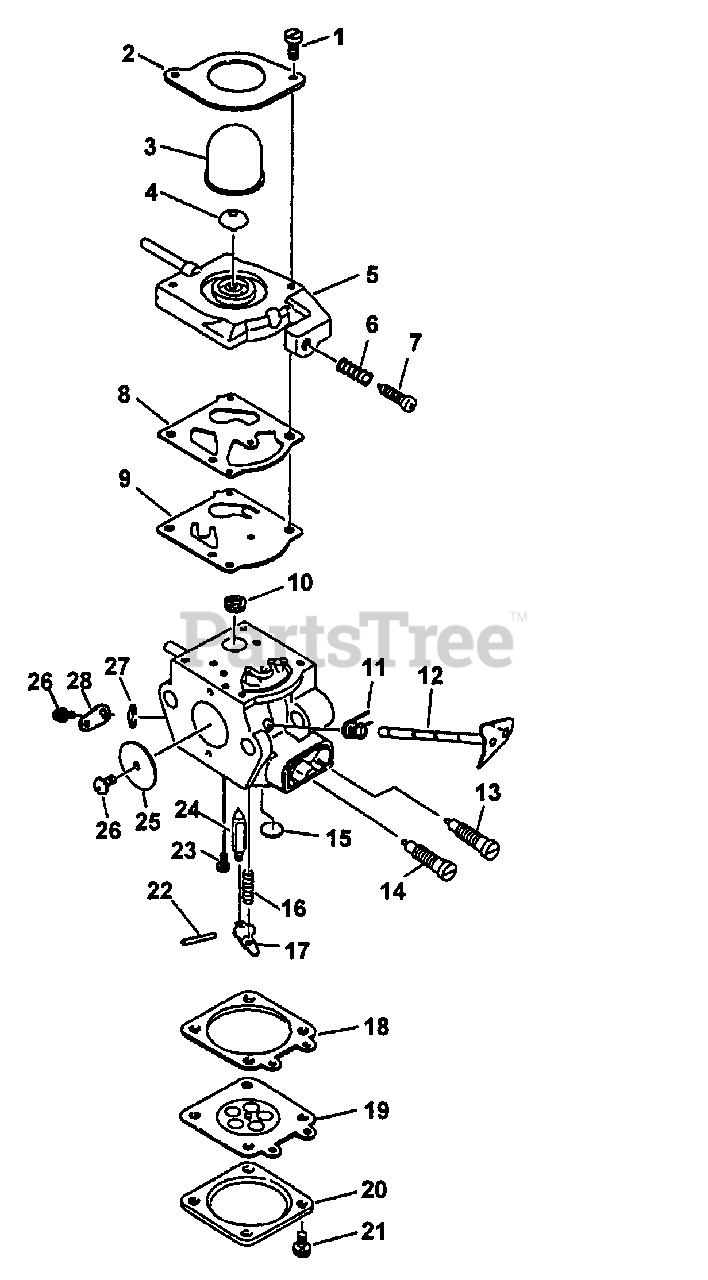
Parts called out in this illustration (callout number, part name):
2	RETAINER, PURGE BULB
3	BULB, PURGE
4	VALVE, CHECK
5	COVER, FUEL PUMP
6	SPRING, IDLE ADJUST
7	SCREW, IDLE ADJUST
10	STRAINER
11	SPRING, THROTTLE RETURN
12	SHAFT ASSY, THROTTLE
13	NEEDLE, HIGH SPEED
14	NEEDLE, IDLE
15	PLUG, WELCH
16	SPRING, METERING LEVER
17	LEVER, METERING
18	GASKET, METERING
19	DIAPHRAGM, METERING
20	COVER, METERING DIAPHRAGM
22	PIN, METERING LEVER
23	SCREW, METERING LEVER PIN
24	VALVE, INLET NEEDLE
25	VALVE, THROTTLE
28	LEVER, THROTTLE
